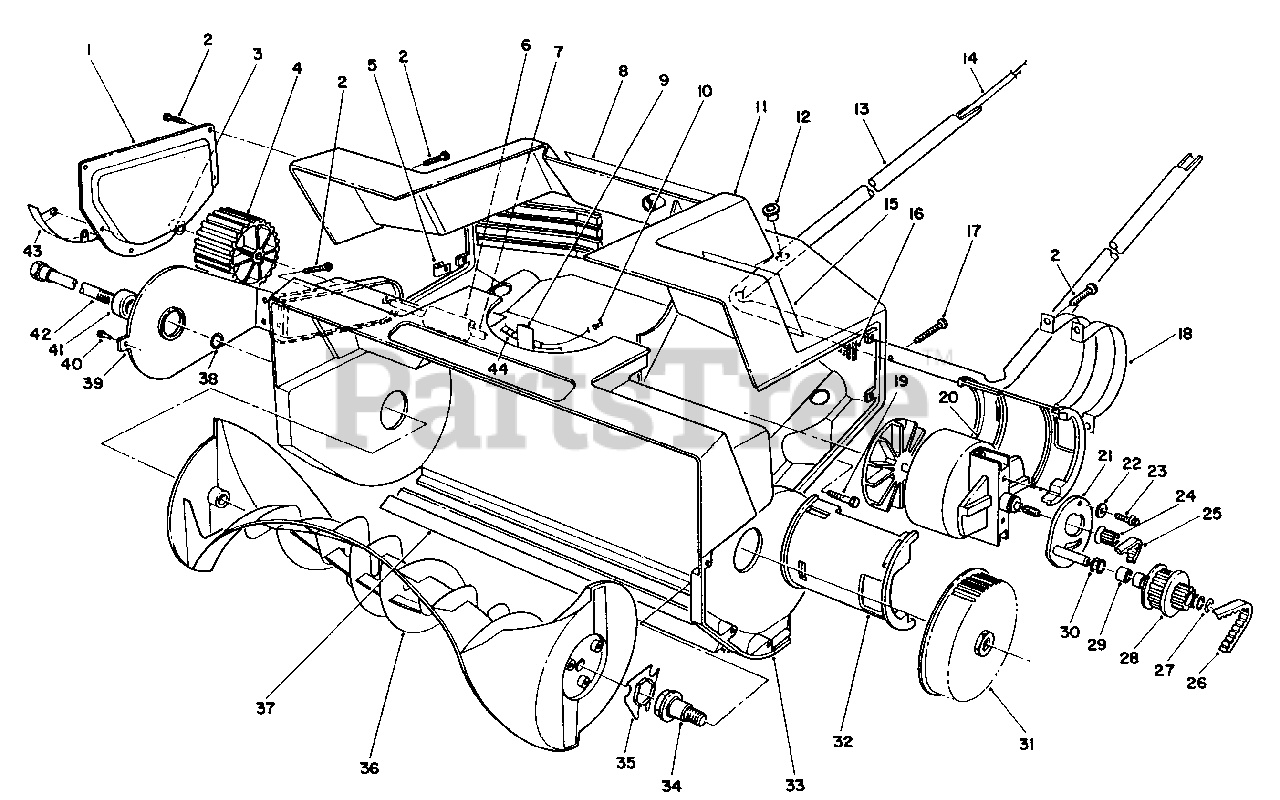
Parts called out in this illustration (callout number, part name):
1	Plate-Side
2	Screw-Pan Hd. Form
3	Push Nut
5	U-Clip-Tinnerman
6	Sleeve-Axle
7	Shaft-Axle
8	Decal-Danger
9	Clip-Cord
10	Connector
11	Shroud-Housing
13	Tube-Lower Handle
14	Wire Harness
15	Decal-Warning
16	Filter-Foam
17	Screw-Pan Hd. Form
18	Strap-Motor
19	Hex Hd. Capscrew
21	Idler Bracket Assembly
22	Flat Washer
23	Hex Washer Hd. Screw
24	Pulley-Driver
25	Belt-Timing
26	Belt-Timing
27	Retaining Ring-External
28	Pulley-Idler (Incl. Ref. #29)
29	Bearing-Needle
30	Washer-Thrust
31	Pulley-Driven
32	Clamp-Motor Bracket
33	Housing-Rotor
34	Shaft-Rotor Driver
35	Coupler-Rotor
36	Rotor
37	Scraper
39	Bracket-Wheel (Incl. Ref. #41)
40	Rivet-Pop
41	Bearing-Ball
42	Shaft-Rotor
43	Skid-Housing
44	Relief-Strain
